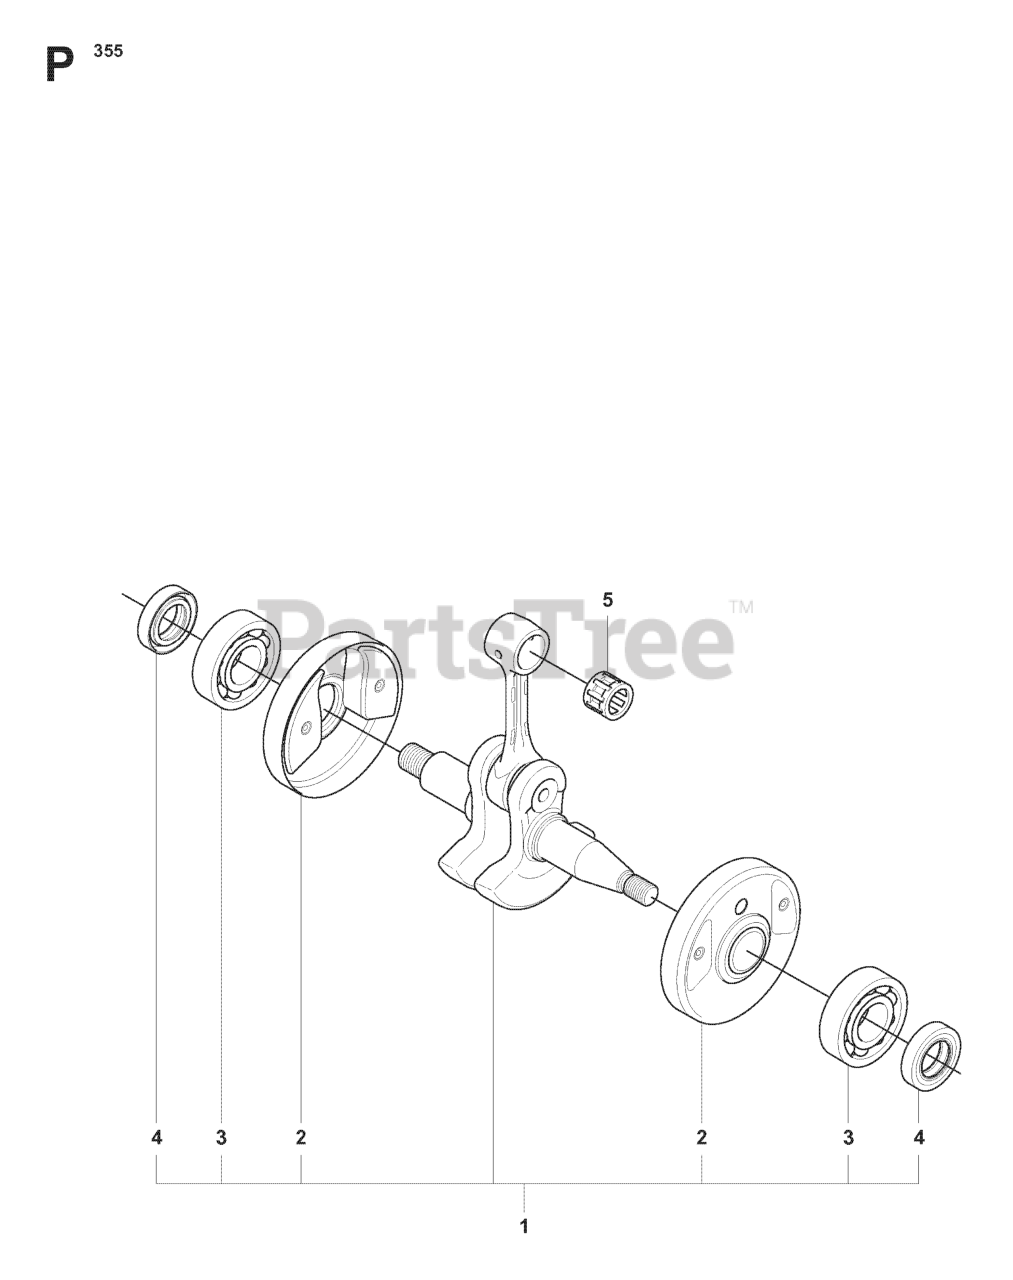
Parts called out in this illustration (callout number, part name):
1	CRANKSHAFT
3	BALL BEARING-6202-C3 SKF
4	SEALING RING
5	SUPPORT BUSHING
